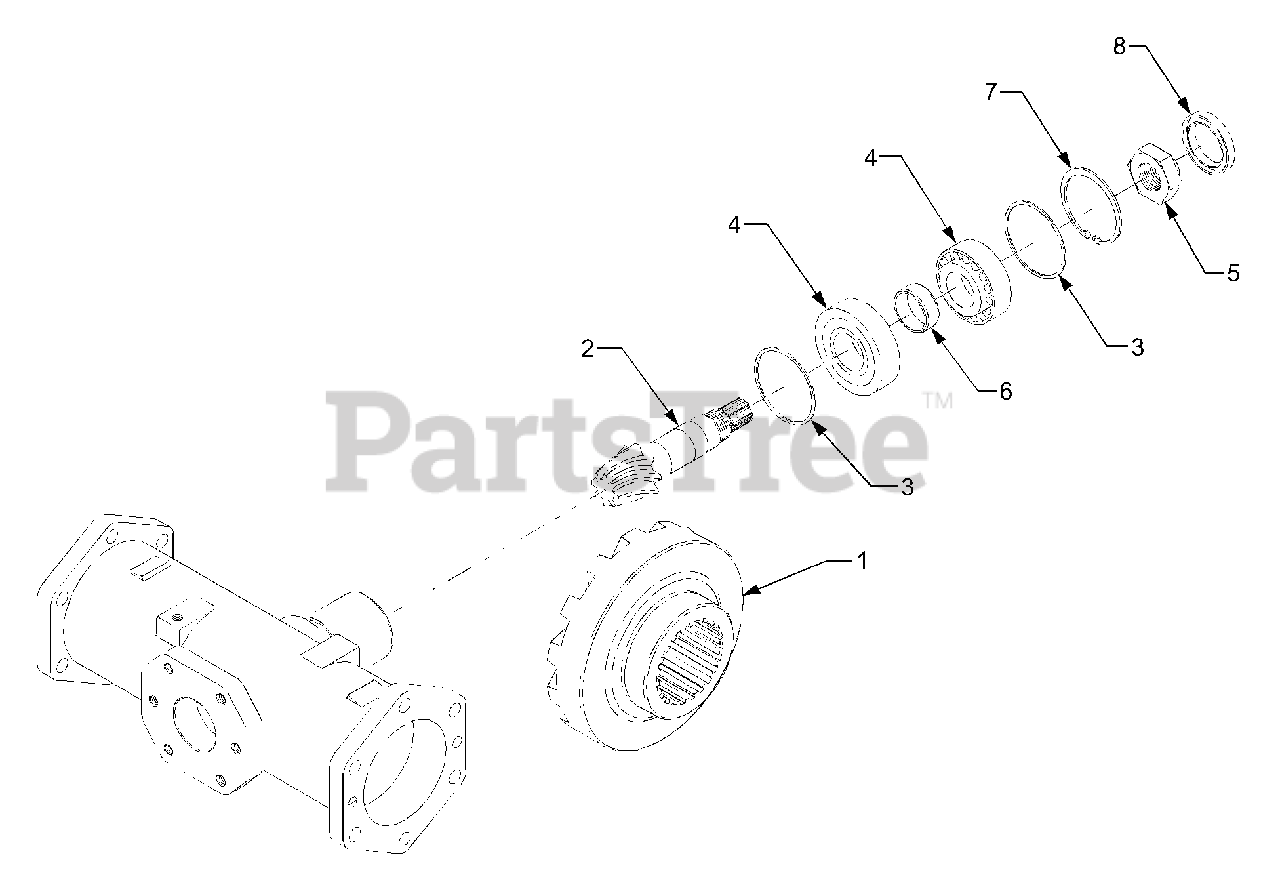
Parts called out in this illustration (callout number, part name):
1	Gear, 23 Spiral Bevel
2	Shaft, 9 Bevel Pinion
3	Collar (T 5.8)
4	Bearing, Taper Roller
